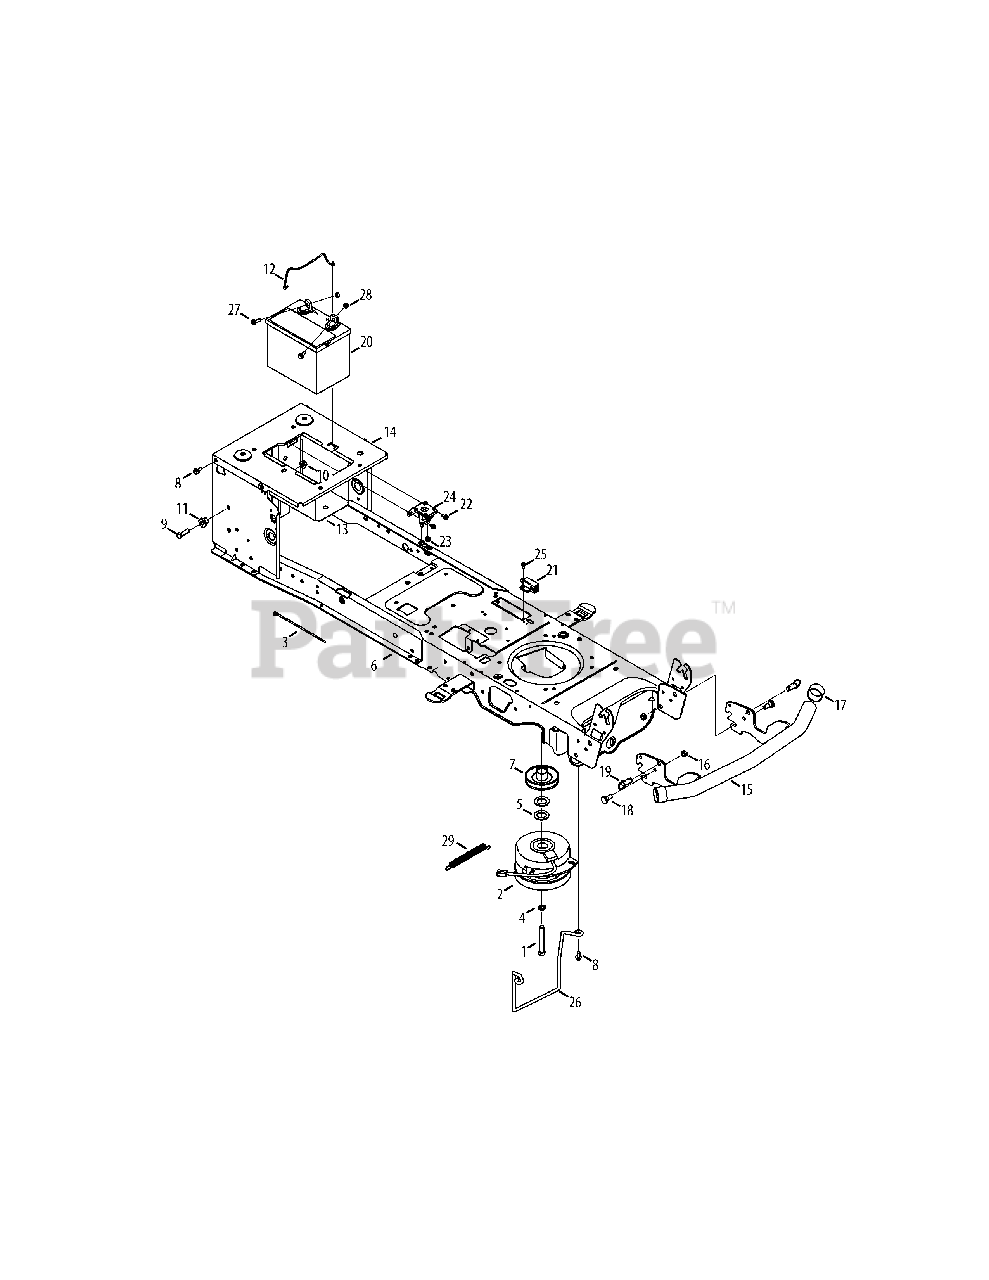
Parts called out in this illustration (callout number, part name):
1	Hex Head Screw, 7/16-20:3.50
2	Electric PTO Clutch
3	Cable Tie, 3/16 x .05 x 7.4
4	Lock Washer, 7/16
5	Flat Washer, 1.031 x 1.620 x .095
6	Frame
7	Electric PTO Engine Pulley
8	Taptite Screw, 5/16-18:.750
9	Hex Head Screw, 3/8-16:1.25
10	Flangelock Nut, 3/8-16
11	Shoulder Spacer, .38 x 1.0 x .70
12	Battery Holder Rod
13	Battery Tray
14	Seat Frame Bracket
16	Hexlock Nut, 3/8-16
17	Bumper Cap
18	Shoulder Bolt, .496 x .336
19	Quick Release Pin
20	Battery
21	Interlock Switch
22	Taptite Screw, 1/4-20:0.375
23	Flangelock Nut, 1/4-20
24	Solenoid, 12 V
25	Shoulder Screw, #10-32:.500
26	Belt Keeper Rod
27	Hex Head Flange, 1/4-20:.75
28	Sems Nut, 1/4-20
29	Spring, Extn, .56 Dia X 5.52
